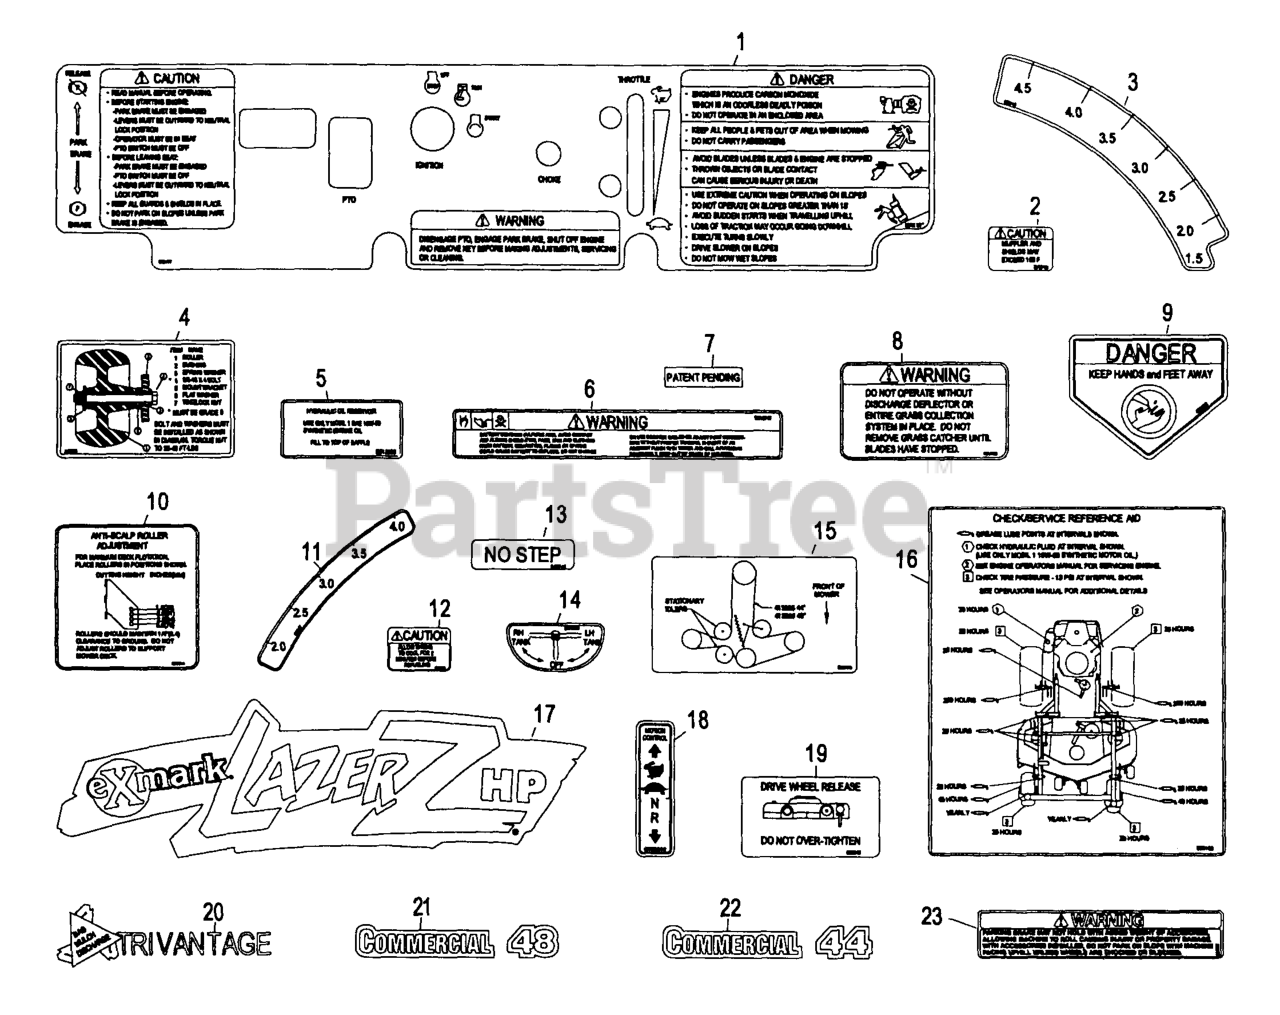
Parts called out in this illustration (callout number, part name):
3	DECAL-DECK HEIGHT, OUTER
4	DECAL,ROLLER MOUNTING
5	DECAL,HYD TANK
6	DECAL-BATTERY
7	Decal, Patent Pending
8	DECAL-WARNING, DISCHARGE
9	DECAL-DANGER
11	DECAL-DECK HEIGHT, INNER
13	DECAL,NO STEP
15	Decal, Belt Routing
19	DECAL,DRIVE RELEASE
21	DECAL,COMMERCIAL 48
22	DECAL,COMMERCIAL 44
23	DECAL,PARK BRAKE WARNING
